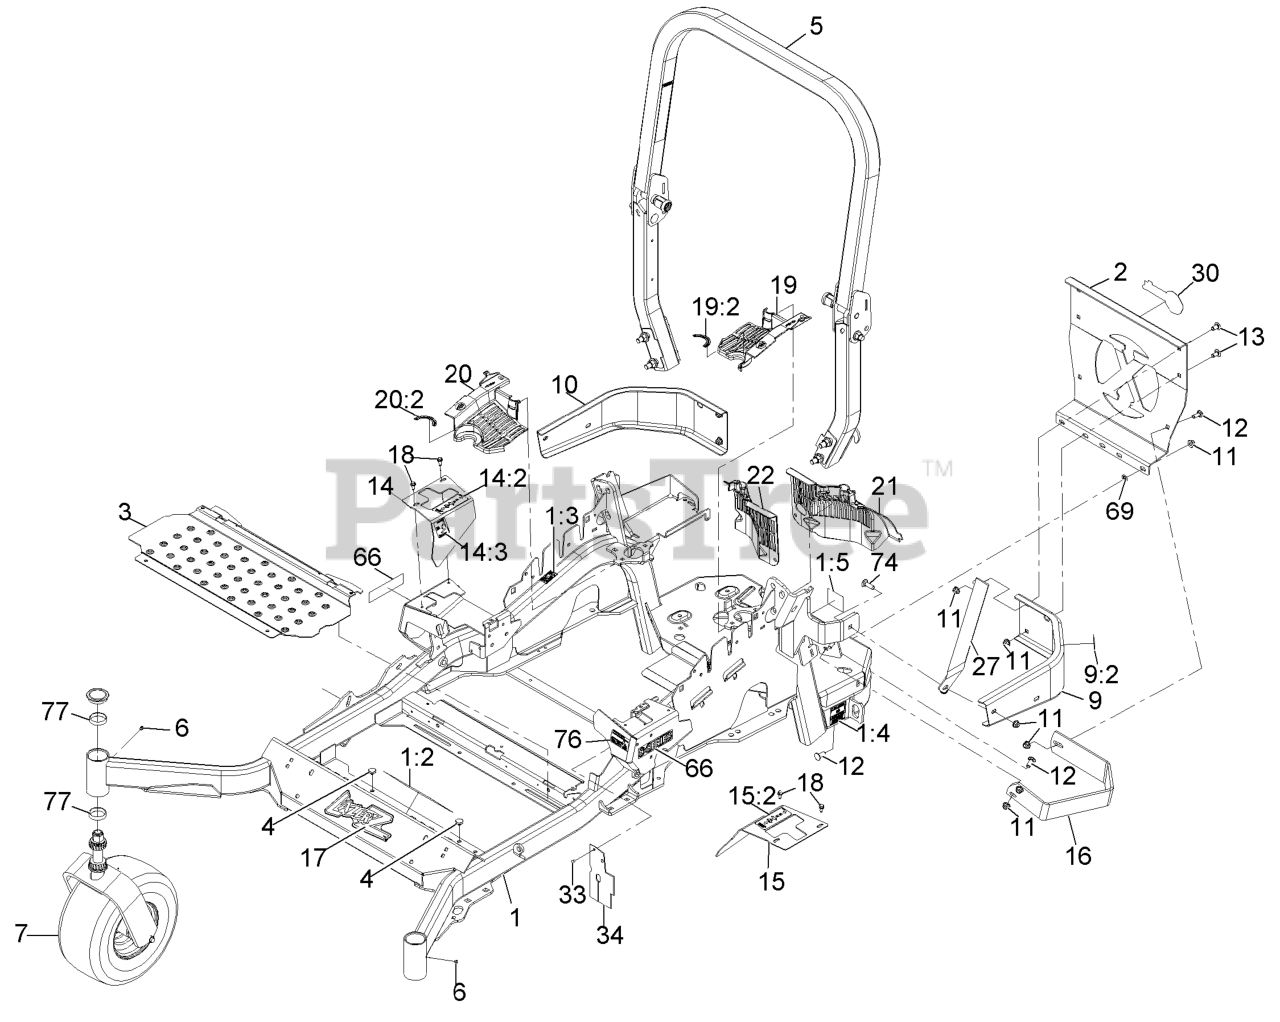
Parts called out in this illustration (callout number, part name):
1	MAINFRAME ASM
1:2	DECAL-SLOPE
1:3	DECAL-CAUTION
1:4	DECAL-BELT DRIVE
1:5	DECAL-SPARK ARRESTER
2	PLATE,REAR GUARD
5	ASM,ROPS SERVICE EXMARK
7	Front Caster And Fork Asm
9	LH BUMPER ASM
9:2	DECAL-CAUTION
10	BUMPER-RH
11	NUT-HF, NI
12	SCREW-CARR
13	SCREW-CARR
14	RH MOTION CONTROL COVER ASM
14:2	DECAL-MOTION CONTROL
14:3	DECAL-PARK BRAKE
15	LH MOTION CONTROL COVER ASM
15:2	DECAL-MOTION CONTROL
16	GUARD-MUFFLER
17	DECAL,LAZER MODEL
18	SCREW-HWH
19	LH HYDRO GUARD ASM
19:2	DECAL-HYDRO OIL
20	RH HYDRO GUARD ASM
20:2	DECAL-HYDRO OIL
21	GUARD-HYDRO, REAR (LH)
22	GUARD-HYDRO, REAR (RH)
33	RIVET-POP
34	DEFLECTOR-AIR FLOW
66	DECAL-S-SERIES
69	NUT-PUSH
74	BOLT-CARR
76	DECAL-FUEL FILL
77	CUP-BEARING
